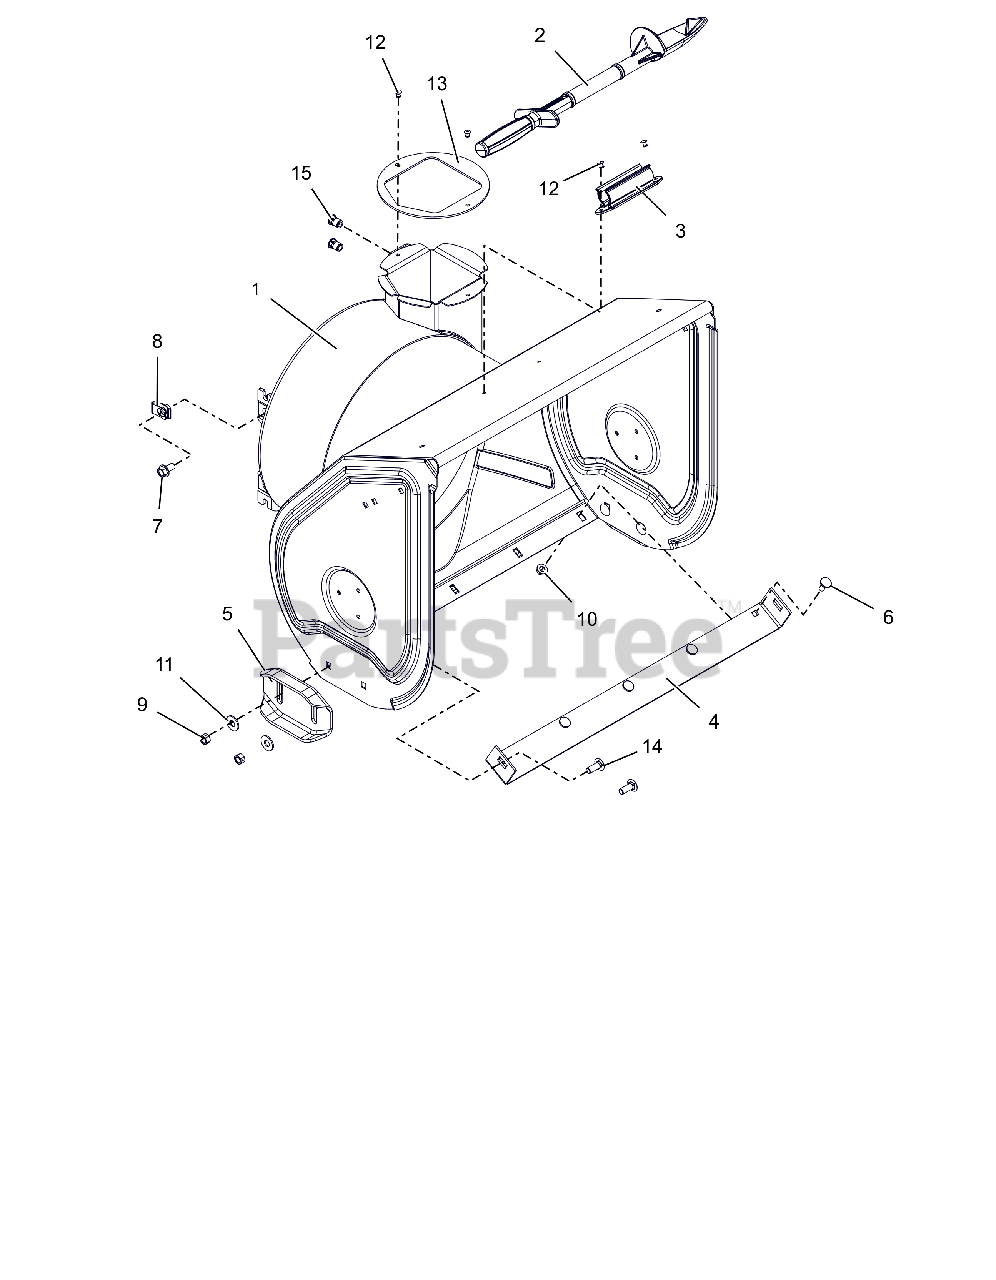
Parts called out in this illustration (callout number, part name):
1	BLOWER HOUSING W/DECAL 24"
2	DEVICE, SNOW CLEAN OUT
3	MOUNT, SNOW CLEAN OUT
4	BLADE, SCRAPER-24"
5	SKID SHOE, REVERSIBLE - ORANGE
6	BOLT, MODIFIED HEAD CARRIAGE
7	BLT-SERHFWH .38-16X.75 YWZC
8	NUT-RTNR .375-16X.37
9	@NUT-LK-CTR .38-16 YWZC
10	@NUT-LK-TOP-FLG .31-18 YWZC
11	@WSHR-FL-STL.438X1.00X.083 YWZ
12	RVT-POP .187 YZ
13	BAFFLE, DISCHARGE NECK
14	@BLT-RDHDSHSQNK.38-16X1.0 G5YZ
15	NUT, THREADED INSERT .38-16
